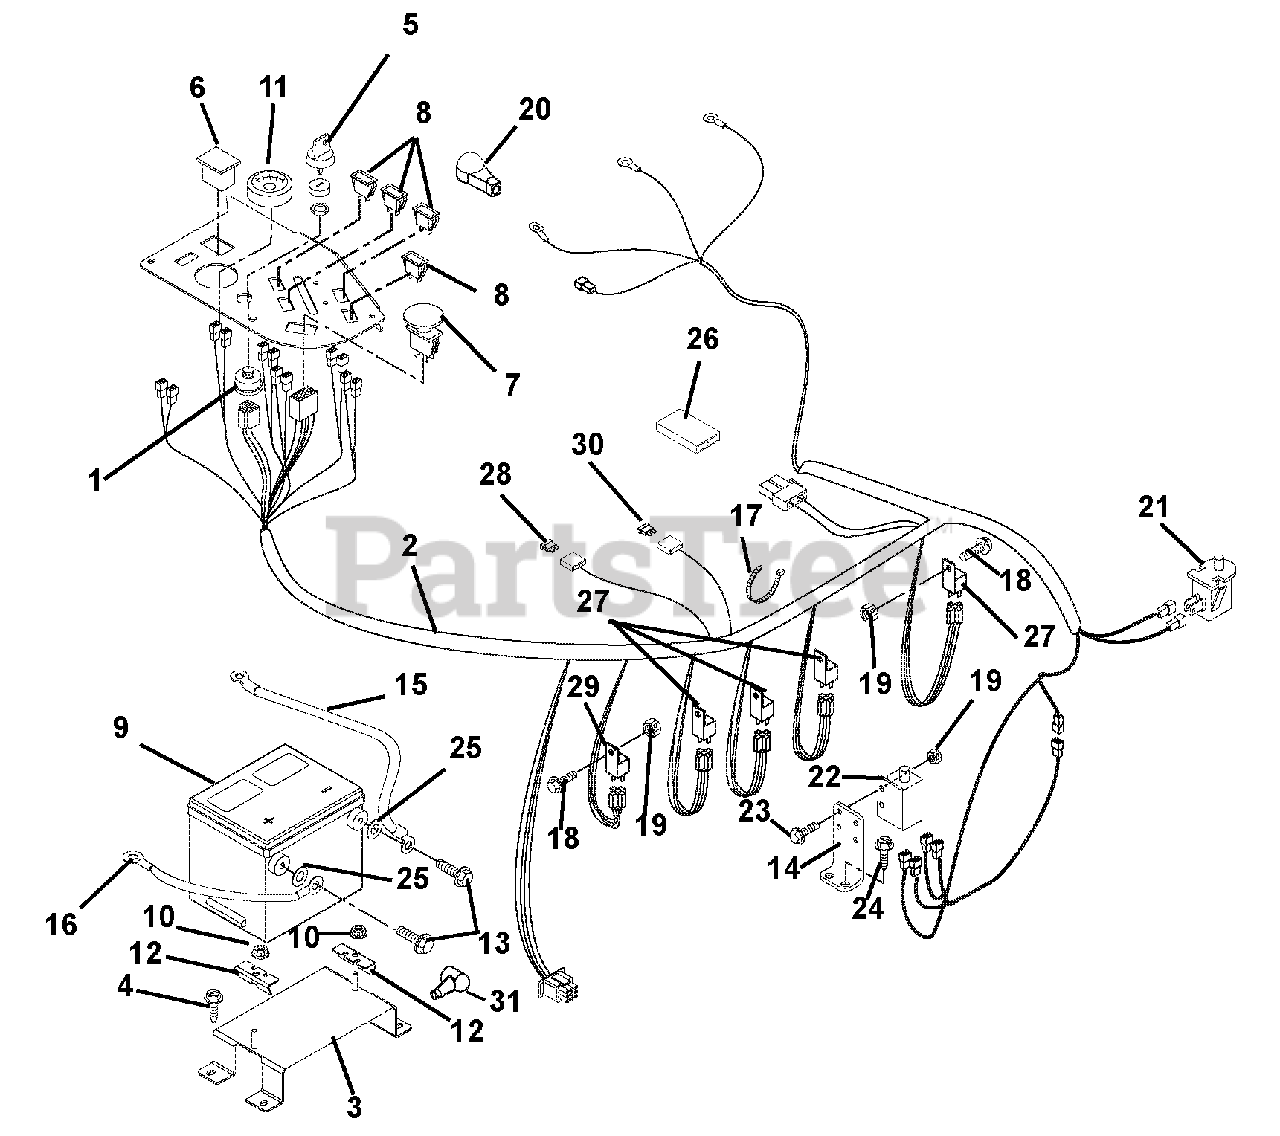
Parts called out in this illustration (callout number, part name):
1	Switch, Ignition
2	Harness, Wiring
3	Weldment, Battery Support
4	Screw, Tapping .38-16 x .75 Hex Washer Head
5	Key, with Cap
6	Hour Meter
7	Switch, Clutch With Retainer Ring
8	Light, Indicator
9	Battery with Tube
10	Nut, Locking Top Flange .31-18
11	Gauge, Temperature
12	Bracket, Battery Hold-Down
13	Bolt, Hex .25-20 x .75 Grade 5
14	Mount, Safety Switch
15	Cable, Positive Battery with Boots
16	Cable, Negative Battery
17	Cable Tie
18	Screw, Machine 10-24 x .75 Hex Washer Head
19	Nut, Locking Nylon 10-24 With Insert
20	Boot Terminal, Red
21	Switch, Snap Mounting (N.O.) (Included with Seat)
22	Switch, Single Pole
23	Screw, Machine 10-24 x .75 Hex Washer Head
24	Screw, Tapping .25-20 x .50 Hex Washer Head
25	Washer, Flat-Steel .406 x 1.00 x ..083
26	Diode, Connector Shell
27	Relay (Included with Harness)
28	Fuse, ATO 30 Amp (Included with Harness)
29	Pre-Heat Timer (Included with Engine)
30	Fuse, ATO 60 Amp (Included with Harness)
31	Battery Terminal Boot, Red
